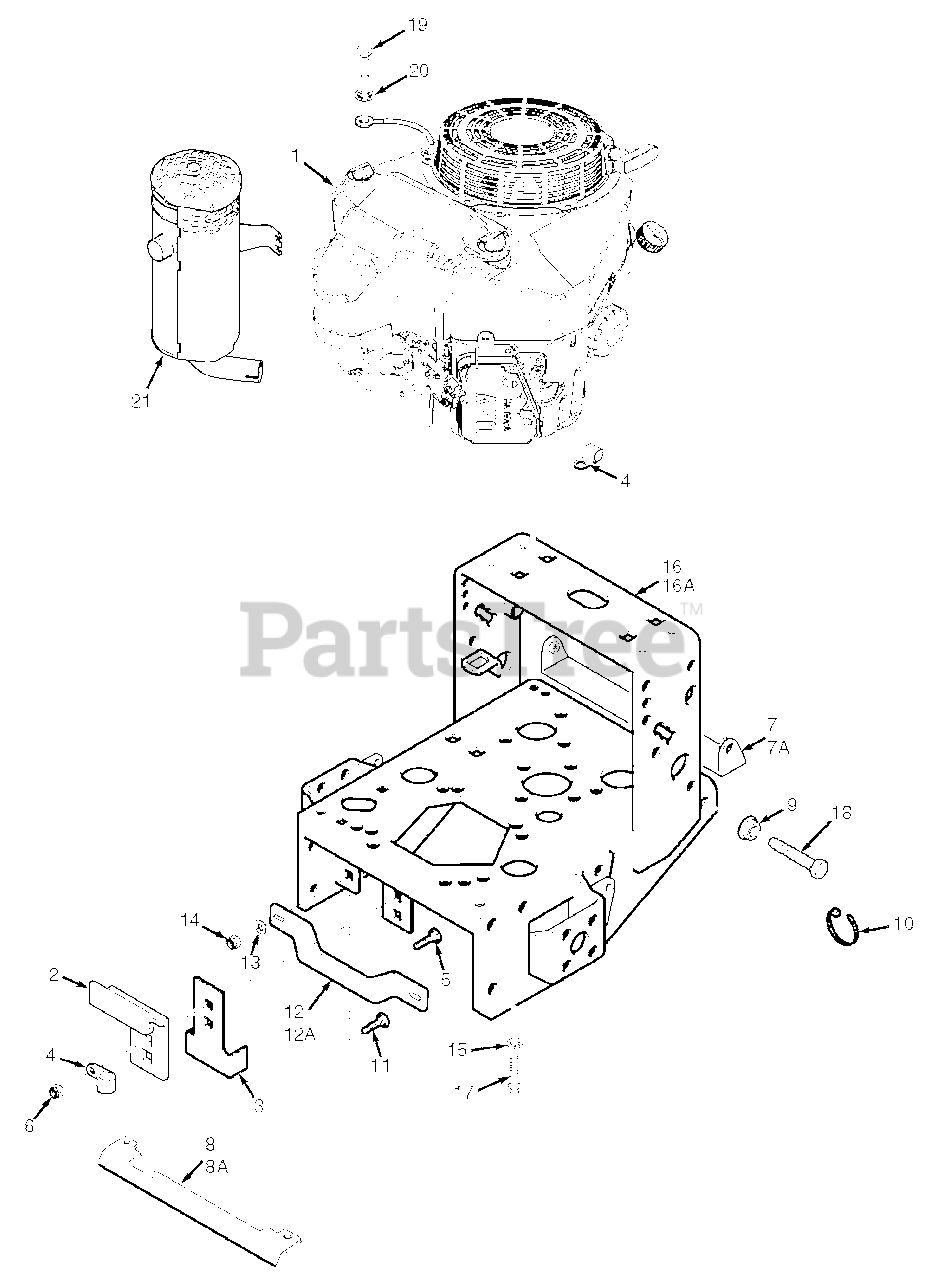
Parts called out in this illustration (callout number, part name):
1	Engine, Kawasaki 14FS (FS481V)
1	Engine, Kawasaki 15FS (FS541V)
1	Engine, Kawasaki 18FS (FS600V)
2	Plate, Clutch Bracket
3	Clutch Bracket
5	Bolt, Carriage 5/16-18 x 1"
6	Nut, 5/16-18 Elastic Stop
7	Pulley Guard, 16" Small Frame
7A	Pulley Guard, 20" Large Frame
8	Heatshield, 16" Small Frame
8A	Heatshield, 20" Large Frame
9	Nut, 5/16-18 Serr. Flange
10	Cable Tie
11	Bolt, Carriage 3/8-16 x 1-1/4"
12	Brace, 16" Small Frame
12A	Brace, 20" Large Frame
13	Flatwasher, .391 x .938 x .105
14	Nut, 3/8-16 Elastic Stop
15	Lockwasher, 3/8"
16	Engine Deck, 16" Wide w/Decals
16A	Engine Deck, 20" Wide w/Decals
17	Bolt, Hex Head 3/8-16 x 1-1/4"
18	Bolt, 5/16-18 x 2" Hex Head
19	Bolt, Hex Head M8-1.25 x 16
20	Lockwasher, 5/16" Ext. Tooth
21	Muffler, Kawasaki FS/FX
